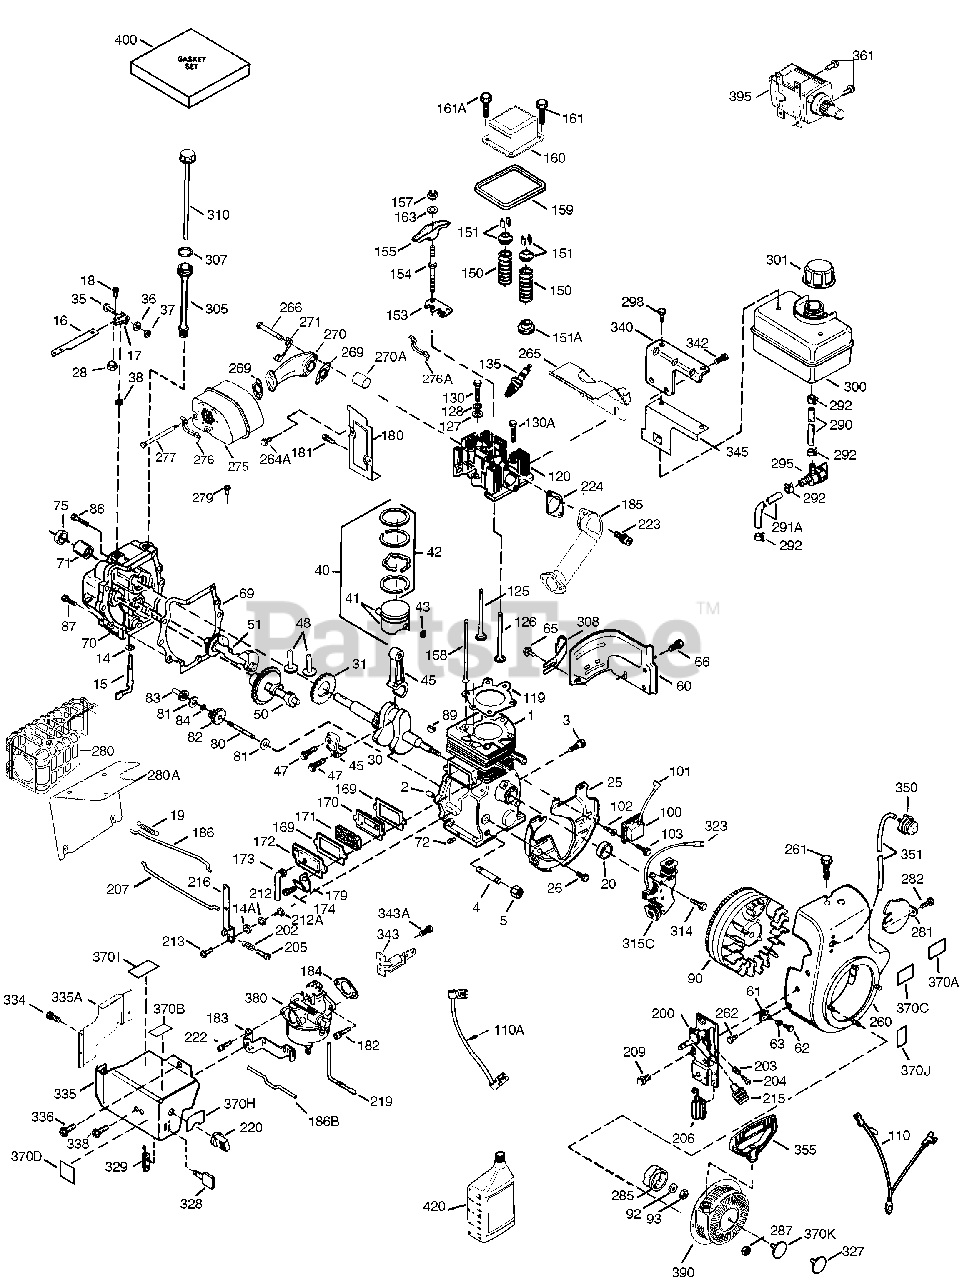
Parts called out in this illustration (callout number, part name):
1	"Cylinder (Incl. 2, 20, 72 & 80)
2	Dowel Pin
3	Screw, 1/4-20 x 1/2"
4	Oil Drain Extension
5	Extension Cap
14	Flat Washer
15	Governor Rod (Incl. 14 & 38)
16	Governor Lever
17	Governor Lever Clamp
18	Screw, Torx T-15, 8-32 x 3/8"
19	Extension Spring
20	Oil Seal
25	Blower Housing Baffle
26	Screw, 1/4-20 x 5/8"
28	Lock Nut, 10-32
30	Crankshaft
31	Counterbalance Gear
35	Screw, 10-32 x 3/4"
36	Lock Washer #8
37	Lock Nut, 10-32
38	Retaining Ring
40	Piston, Pin & Ring Set (Std) (Incl. 4 1, 42 & 43)
40	Piston, Pin & Ring Set (.010" OS) (In cl. 41, 42 & 43)
40	Piston, Pin & Ring Set (.020" OS) (In cl. 41, 42 & 43)
41	Piston & Pin Assembly (Std) (Incl. 43 )
41	Piston & Pin Ass'y. (.010" OS) (Incl. 43)
41	Piston & Pin Ass'y. (.020" OS) (Incl. 43)
42	Ring Set (Std.) (3-5/16")
42	Ring Set (.010" OS)
42	Ring Set (.020" OS)
43	Piston Pin Retaining Ring
45	Connecting Rod Ass'y (Incl. 47)
47	Connecting Rod Bolt
48	Valve Lifter
50	Camshaft (MCR)
51	Counterbalance Weight
60	Blower Housing Extension
65	Screw, 10-24 x 9/16"
69	* Cylinder Cover Gasket
70	Cylinder Cover (Incl. 14, 15, 38, 71 & 75)
71	Crankshaft Bushing
80	Governor Shaft
81	WASHER
82	Governor Gear Assembly
83	Governor Spool
84	Retaining Ring
86	Screw, 1/4-20 x 1-3/16"
87	Screw, 1/4-20 x 1-11/16"
89	Flywheel Key
90	Flywheel (W/Ring Gear)
92	Lock Washer
93	Flywheel Nut
100	Solid State Ignition
101	Spark Plug Cover
102	Solid State Mounting Stud
103	Screw, Torx T-15, 10-24 x 15/16"
110	Ground Wire
110A	Ground Wire (10.50" with male & femal e flag terminals)
119	* Cylinder Head Gasket
120	Cyinder Head
124	Screw, 1/4-20 x 5/8"
125	Exhaust Valve (Std.)
125	Exhaust Valve (1/32" OS)
126	Intake Valve (Std.)
126	Intake Valve (1/32" OS)
128	Belleville Washer
130	Screw, 5/16-18 x 2-1/2"
135	Resistor Spark Plug (RN4C) also avail able in Packaged Part #740069
150	Valve Spring
151	Valve Spring Keeper
153	Push Rod Guide
154	Rocker Arm Stud
155	Rocker Arm
157	Jam Nut
158	Push Rod
159	* Rocker Arm Cover Gasket
160	Rocker Arm Cover
161	Screw, T-30, 1/4-20 x 1/2"
161A	Valve Cover Mounting Stud
163	Lock Washer
169	* Valve Cover Gasket
170	Breather Body
171	Breather Element
172	Valve Cover
173	Breather Tube
174	Screw, 10-24 x 1/2"
178	Nut & Lock Washer 1/4-28
180	Blower Housing Extension
183	Choke Bracket
184	* Carburetor To Intake Pipe Gasket
185	Intake Pipe
186	Governor Link
186B	Choke Spring
200	Manual Control Bracket (Incl. 203, 20 4 & 206)
203	Compression Spring
204	Screw, Torx T-10, 6-32 x 41/64"
204	Screw, Torx T-10, 5-40 x 7/16"
206	Terminal
207	Throttle Link
212	Bushing
213	Screw, 10-32 x 5/8"
215	Control Knob
216	R.P.M. Adjusting Lever
219	Choke Rod
220	Control Knob
222	Screw, 10-32 x 1/2"
223	Screw, Torx T-30, 5/16-18 x 7/8"
224	* Intake Pipe Gasket
254A	Rocker Arm Stud/Bearing Kit (incl. re f. 155, 156, & 157)
260	Blower Housing
262	Screw, T-40, 5/16-24 x 21/32"
265	Cylinder Head Cover
266	Screw, 5/16-18 x 1-9/32"
269	* Exhaust Gasket
270	Exhaust Manifold
270A	Exhaust Port Liner
271	Locking Plate (Manifold)
275	Muffler
276	Locking Plate
277A	Screw, 5/16-18 x 4-1/2"
280	Heat Shield
285	Starter Cup
291	Fuel Line
292	Fuel Line Clamp
293A	Screw, Torx T-30, 1/4-20 x 27/32"
298	Screw, 1/4-15 x 3/4"
300	Fuel Tank (Incl. 292 & 301)
301	Fuel Cap
305	Oil Fill Tube
307	"O" Ring
308	Fill Tube Clip
309	Screw, 10-32 x 5/16"
310	Dipstick
314	Screw, 1/4-20 x 3/4"
323	Terminal
327	Starter Plug
328	Ignition Key
335	Carburetor Cover (Front)
335A	Carburetor Cover
338	Screw, 10-32 x 1/2"
342A	Screw, 5/16-18 x 7/8"
343	Key Switch Bracket
345	Heat Baffle
350	Primer Assembly (also available in Pa ckaged Part #740101)
351	Primer Line
355	Starter Handle (Mitten Grip) also ava ilable in Packaged Part #740053B
361	Screw, Torx T-30, 1/4-20 x 15/32"
370	Decal - Start Instrucitons - Warning - Hot Areas
370	Decal - Primer - International Symbol
370	Decal - Speed Control, Choke, & Key
380	Carburetor (Incl. 184)
390	Rewind Starter Note: This engine cou ld hav e been built with 590733 start er.
395	Electric Starter Motor (120 Volt)
400	Gasket Set (Incl. items marked PK in notes) Incl. part #'s 27896A (2),332 63 (1),33515A (1),35317 (1),35683 (1) ,35762 (2),35952 (1), 36333 (1),36352 (1),36358 (1),36832 (1),36930 (1 ),3 6932 (1),36942 (1)
900	Replacement Engine None.
900	Replacement Short Block 758216, order from 71-999
999	Winter Maintenance Kit incl. 5W30 Oil , Spark Plug, Key & Ultra-Fresh
999	Winter Maintenance Kit (incl. 0W30 Sy nthetic Oil, Spark Plug, Key & Ultra- Fresh)
